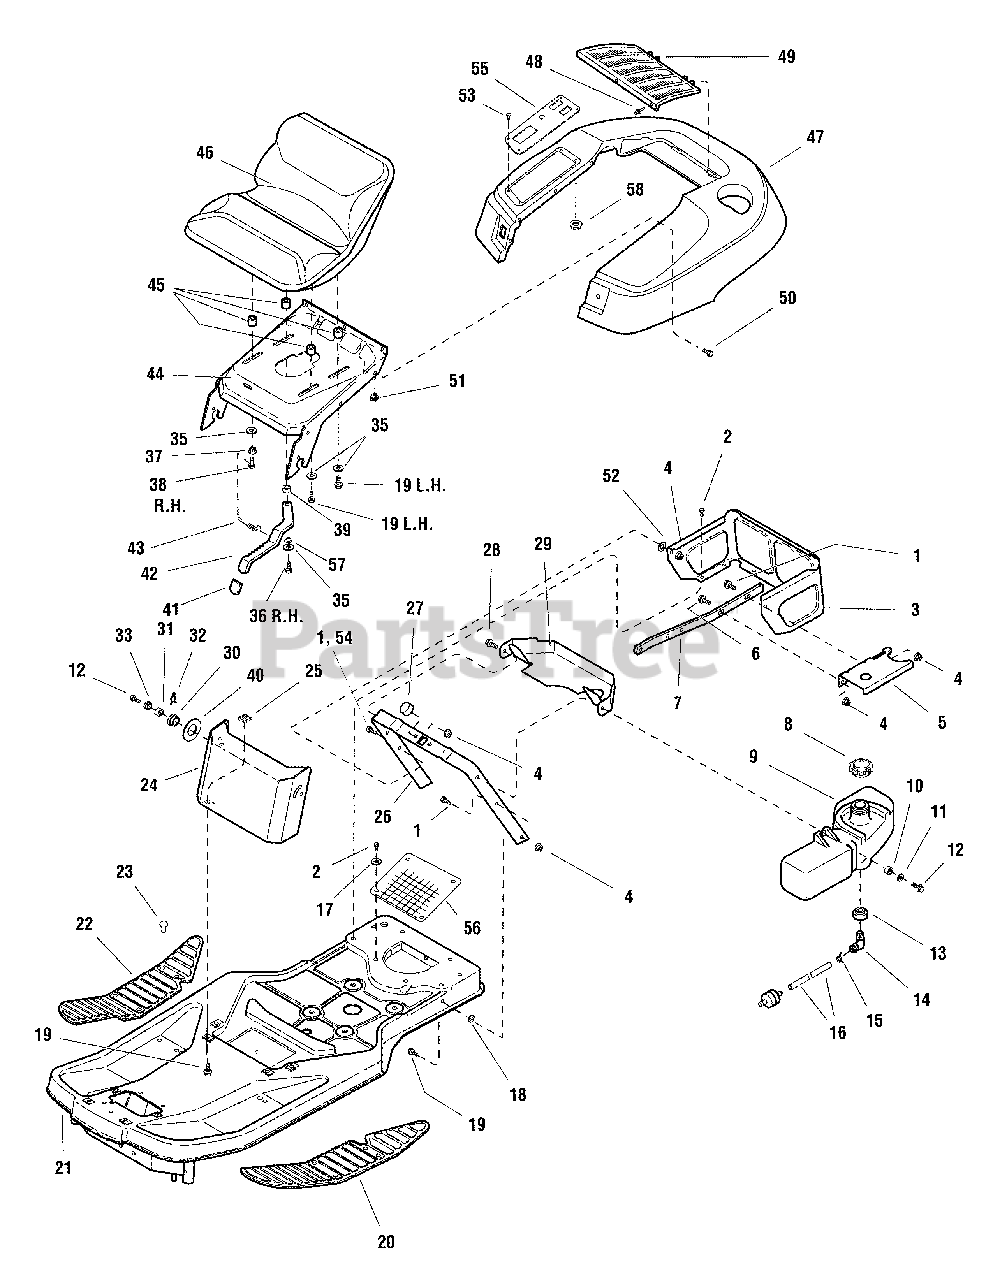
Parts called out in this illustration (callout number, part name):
1	CAPSCREW, Hex Head, 5/16-18 x 1
2	CAPSCREW, Hex Head, Taptite, 1/4-20 x 1/2
3	SHROUD, Rear
4	NUT, Hex, Flange, Whizlock, 5/16-18
5	SUPPORT, Fuel Tank
6	CARRIAGE BOLT, 5/16-18 x 3/4
7	STRAP, Fuel Tank, Brace
8	CAP, Fuel Tank, Vented
9	TANK, Fuel
10	SPACER, 21/64 x 1/2 x 21/64
11	WASHER, Plain, 13/32 x 7/8 x 5/64
12	CAPSCREW, Hex, Taptite, 5/16-18 x 1 Black (13 HP Models)
13	BUSHING, Rubber
14	ELBOW, Fitting with Screen
15	CLAMP, Hose
16	HOSE, Fuel Line
17	WASHER, Plain
18	PUSH NUT, 5/16
19	CAPSCREW, Hex Head, Whizlock, 5/16-18 x 3/4
20	PAD, Foot Rest, LH
21	FRAME ASSEMBLY
22	PAD, Foot Rest, RH
23	FASTENER
24	PANEL, Front
25	NUT, Speed, Lug Type, 5/16-18
26	SUPPORT, U , Seat (13 HP Models)
27	BUMPER, Rubber
28	CAPSCREW, Hex Head, Taptite, 5/16 x 1/2
29	DUCT, Air Inlet (13 HP Models)
30	SPACER, Plastic
31	SPACER
32	PIN, Quick
33	PIVOT, Hood
35	WASHER
36	CAPSCREW, Hex Head, 5/16-18 x 1-1/2
37	NUT, Hex, 5/16-18
38	CAPSCREW, 5/16-18 x 1-1/4
39	SPACER
40	WASHER, 1
41	CAP, Black, Vinyl
42	ADJUSTER, Seat
43	SPRING, Extension
44	SUPPORT, Seat
45	SPACER
46	SEAT ASSEMBLY
47	DECK, Seat, Red
48	RIVET
49	SCREEN, Seat Deck Top
50	CAPSCREW, Hex Head, Whizlock, 1/4-20 x 5/8
51	NUT, Hex, Flange Lock, 1/4-20
52	WASHER, 5/16
53	SCREW, Truss Head, 1/4-20 x 3/4
55	PLATE, Control
56	SCREEN
57	WASHER, 11/32 x 1 x 1/8
58	NUT, ESNA 1/4-20
